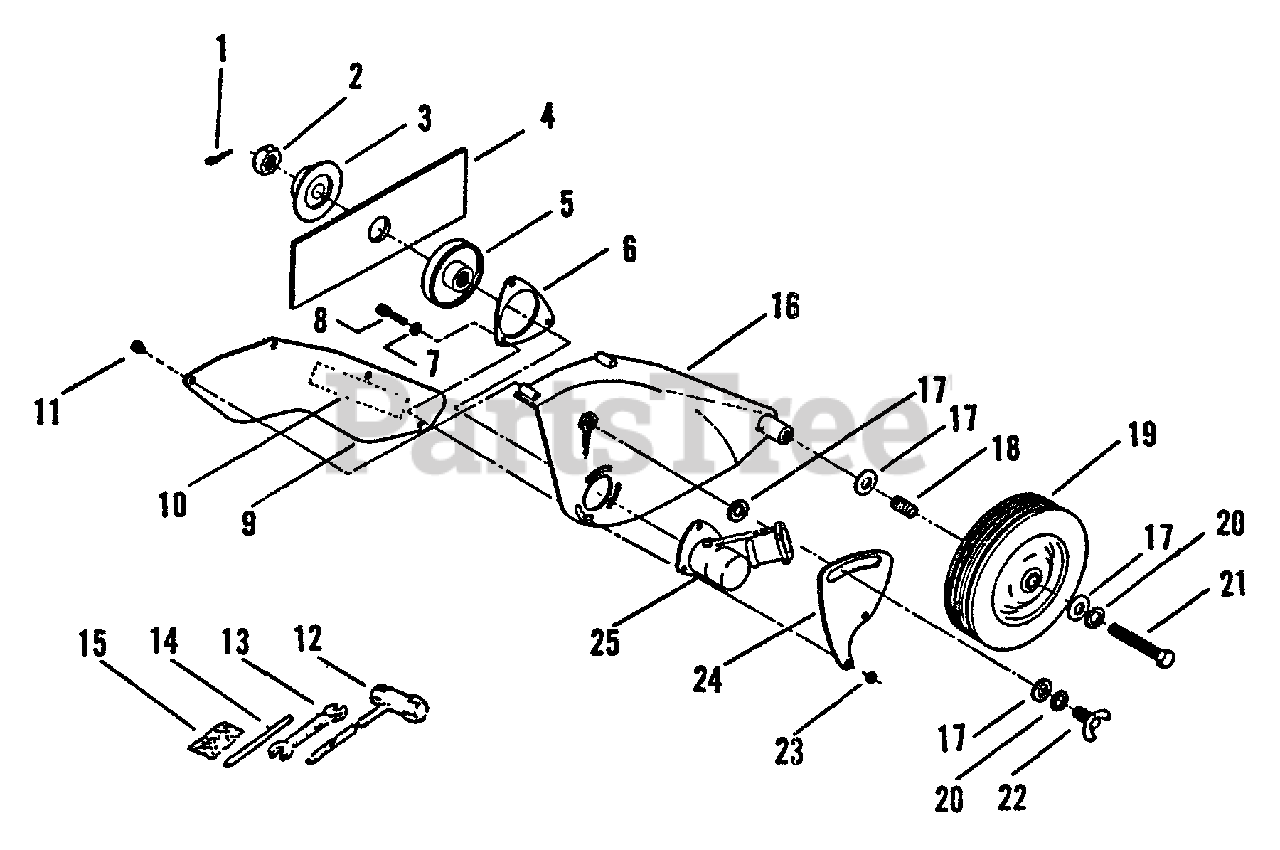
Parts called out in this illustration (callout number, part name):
1	PIN, COTTER 2×22
3	PLATE, ADAPTOR - LOWER
4	BLADE, EDGER
5	PLATE, ADAPTER - UPPER
6	PLATE, SHIELD Ø49.5 MM
7	BOLT 5×25
8	WASHER, CONE 5.2 MM
9	SHIELD ASSY, W/DECAL
10	LABEL - CAUTION
11	BOLT 4×10
12	T-WRENCH 17x-19 L200
13	SPANNER 8×10
14	TOOL, LOCKING 5×120 MM
15	PIN, COTTER 2×22 (PKG. OF 10)
16	WEAR PLATE
18	COLLAR 12
19	WHEEL - 6×1.5
20	WASHER, FLAT 5.5×10×0.8
21	BOLT - 8×60
22	THUMBSCREW - 8×20
23	NUT, LOCK M5
24	BRACKET, SHIELD
25	GEAR CASE ASSY
